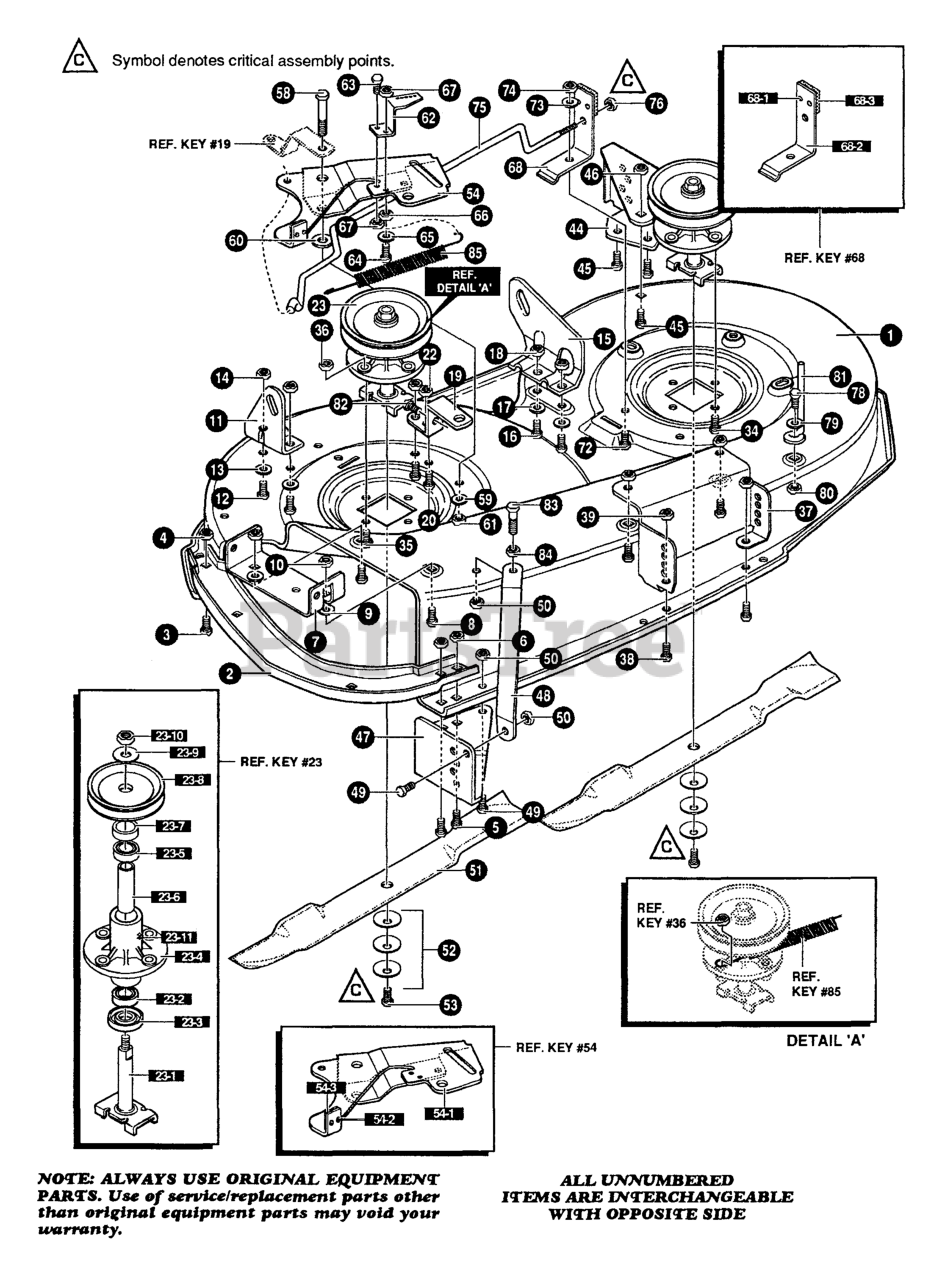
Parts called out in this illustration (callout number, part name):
1	43" DECK KIT
2	TOE GUARD
3	SCREW, 5/16-18 x 0.75
4	NUT, 5/16-18
5	SCREW, 5/16-18 x 0.75
6	NUT, 5/16-18
7	BRACKET, CHUTE MOUNT
8	SCREW, 5/16-18 x 0.75
9	WASHER, FLAT .344 x .69 x .065
10	NUT, 5/16-18
11	BRACKET, RH, LIFT REAR
12	SCREW, 5/16-18 x 0.75
13	WASHER, FLAT .344 x .69 x .065
14	NUT, 5/16-18
15	BRACKET, LH, LIFT REAR
16	SCREW, 5/16-18 x 0.75
17	WASHER, FLAT .344 x .69 x .065
18	NUT, 5/16-18
19	BRACE, IDLER SUPPORT
20	SCREW, 5/16-18 x 0.75
22	NUT, 5/16-18
23	QUILL, W/ZERKS
23-1	SHAFT/SADDLE
23-2	BEARING, BALL
23-3	DUST SHIELD
23-4	QUILL HSG EXP
23-5	BEARING, BALL
23-6	SPACER, SLEEVE .669 x .88 x 3.797
23-7	SPACER, QUILL
23-8	PULLEY, QUILL, VSL
23-9	WASHER, SPECIAL QUILL
23-10	NUT, 7/16-20
23-11	ZERK, GREASE FITTING
34	SCREW, 5/16-18 x 0.75
35	SCREW, 5/16-18 x 1.38
36	NUT, 5/16-18
37	BRACKET FRONT
38	SCREW, 5/16-18 x 0.75
39	NUT, 5/16-18
44	BRACKET, GAGE WHEEL, LH
45	SCREW, 5/16-18 x 0.75
46	NUT, 5/16-18
47	BRACKET, GAGE WHEEL, RH, FRONT
48	BRACKET, STABILIZER
49	SCREW, 5/16-18 x 0.75
50	NUT, 5/16-18
51	BLADE, 21.70
52	WASHER, .39 ID X 1.25 D X .07
53	SCREW, 3/8-24 X 1.25
54	IDLER ARM ASSEMBLY
54-1	ARM, IDLER
54-2	RIVET
54-3	BRAKE PAD
58	BOLT, .500 X 2.15
59	WASHER, FLAT .391 x 1.00 x .125
60	WASHER, FLAT .391 x 1.00 x .209
61	NUT, 3/8-16
62	BRACKET, EXTENSION IDLER
63	SCREW, 5/16-18 x 0.75
64	SCREW, 5/16-18 x 1.50
65	WASHER, FLAT .375 X .88 X .082
66	NUT, 5/16-18
67	NUT, 5/16-18
68	BLADE BRAKE ASSEMBLY
68-2	BRAKE ARM
68-3	BRAKE PAD
72	SCREW, 5/16-18 x 0.75
73	WASHER, FLAT .344 X .69 X .065
74	NUT, 5/16-18
75	ROD, BRAKE
76	NUT, 1/4-20
78	SCREW, 5/16-18 x 1.00
79	WASHER, FLAT .344 x .69 x .065
80	NUT, 5/16-18
81	BELT GUIDE
82	SCREW, 1/4-20 x 1.25
83	SCREW, 5/16-18 x 5.00
84	NUT, 5/16-18
85	SPRING
